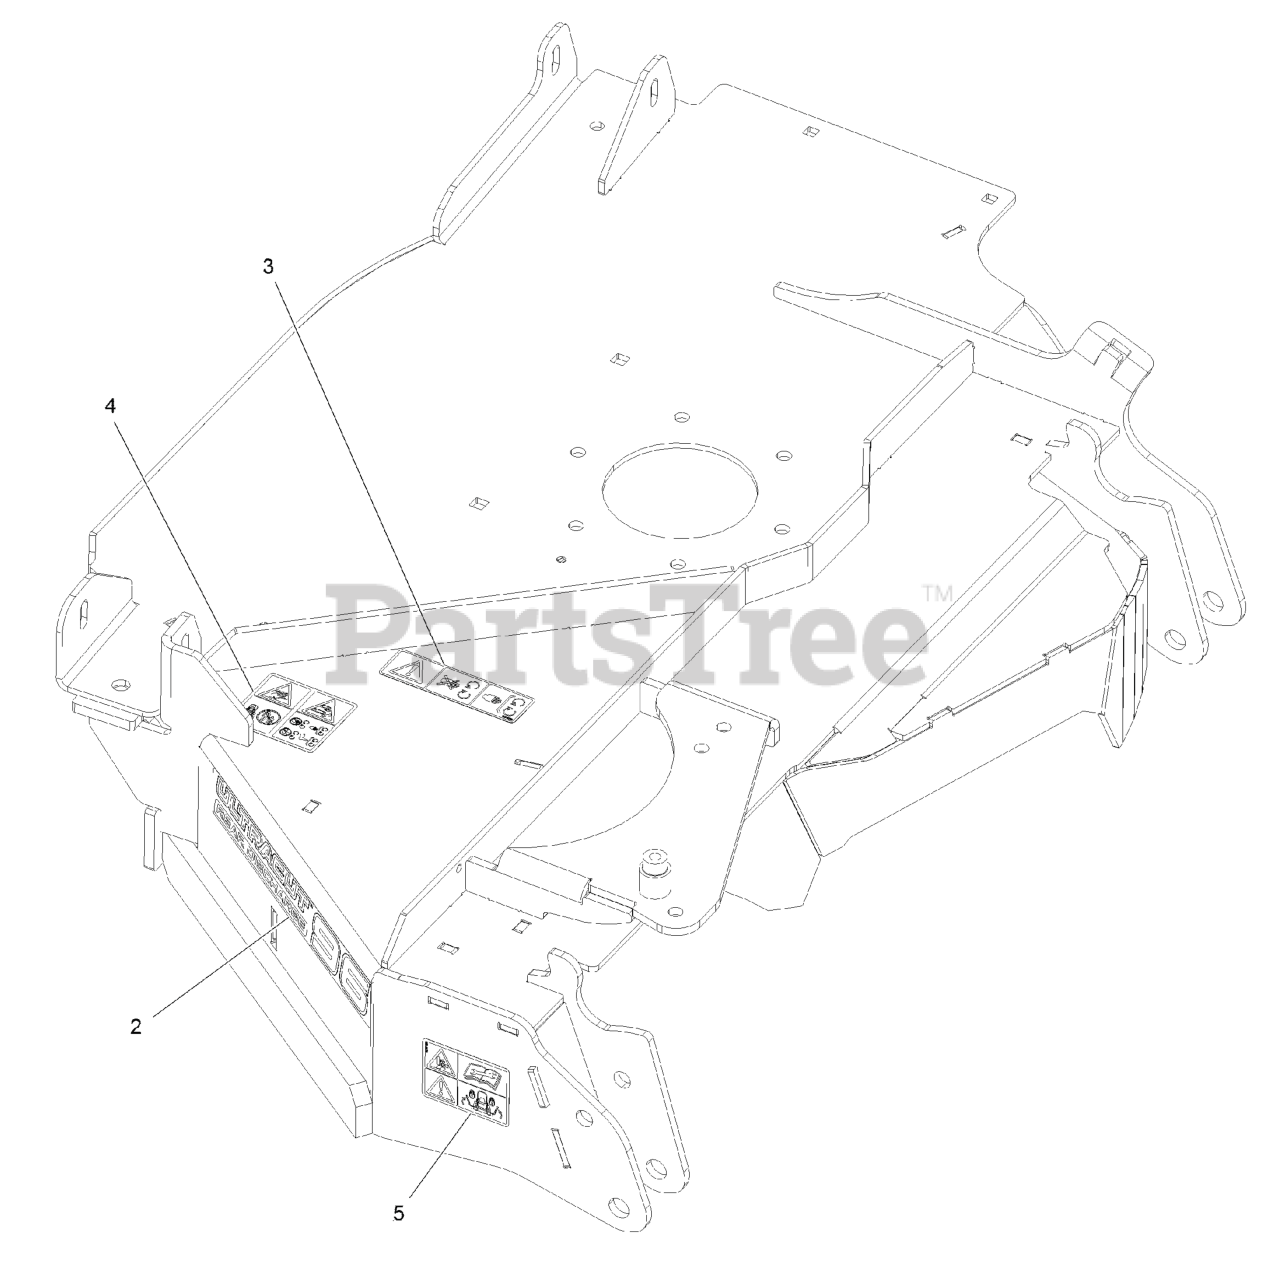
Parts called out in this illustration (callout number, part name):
2	DECAL-ULTRACUT 96-RD
3	DECAL-COVER, MISSING
4	DECAL-DANGER, THROWN OBJECT
5	DECAL-WARNING, PINCH POIN
